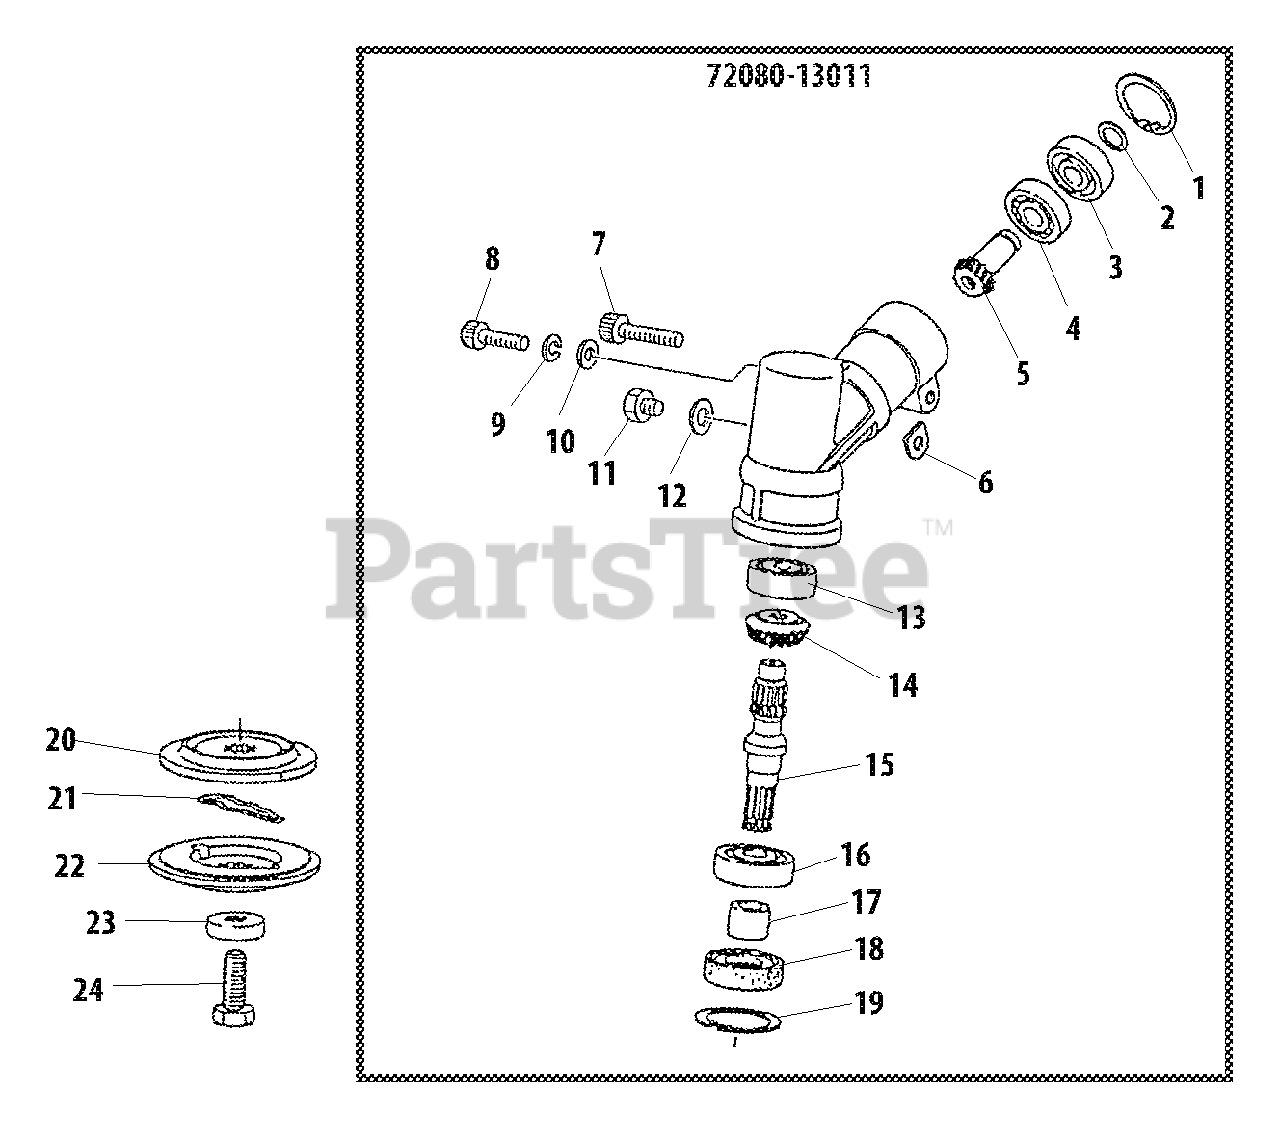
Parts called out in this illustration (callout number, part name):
1	RING, RETAINING - 28
2	RING, RETAINING
3	BEARING, BALL - 6001ZZ
4	BEARING, BALL - 6001
5	GEAR - SHAFT
6	SHIM
7	SCREW - 6X28
8	SCREW - 6X12
9	LOCKWASHER - 6
10	WASHER - 6
11	BOLT - 6X10
12	WASHER
13	BEARING, BALL - 6000DDU
14	GEAR - BEVEL
15	GEAR - SHAFT
16	BEARING, BALL - 6202
17	COLLAR
18	SEAL, OIL
19	RING, RETAINING - 35
20	HOLDER (A)
21	SLIDE PIN
22	HOLDER (B)
23	GUARD
24	BOLT - 10 -- LEFT HAND
72080-13011	GEAR CASE ASSY
